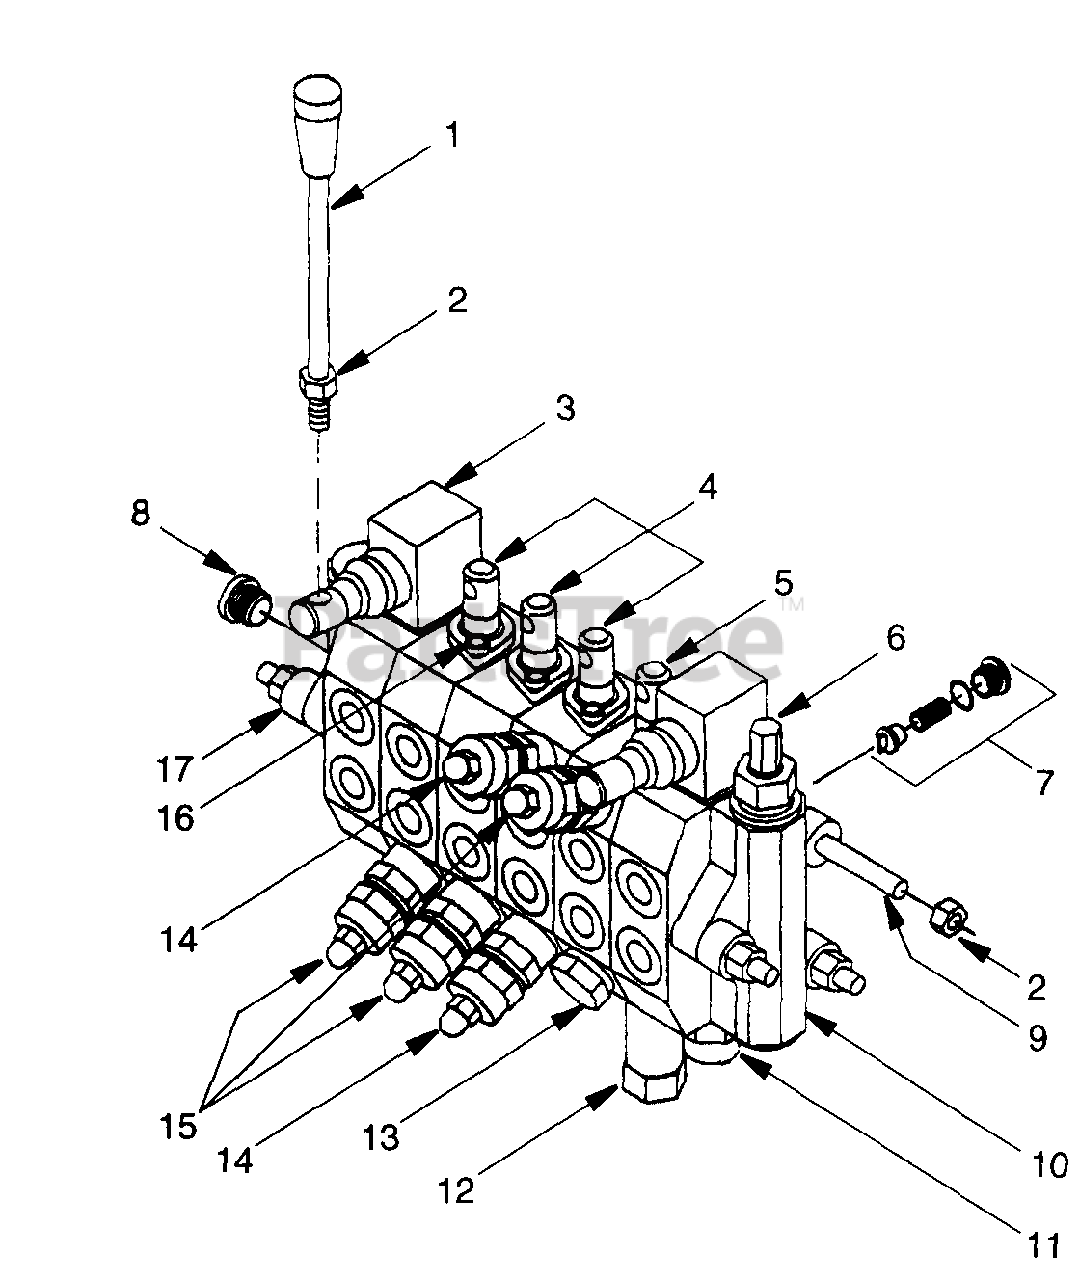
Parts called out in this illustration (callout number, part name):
1	Stabilizer Control Handle
2	Hex Nut, 8mm x 1.25P
3	Stabilizer Control Assy
4	Valve Spool Section w/Out Relief
5	Boom Section w/Relief
6	Relief Valve Assy
7	Check Valve Assy
8	Plug, 3/4 SAE M w/O-ring
9	Hex Hd Cap Scrw, 8mm x1.25P x 276mm
10	Valve Inlet Section
11	Spool Position Control Assy
12	Spool Position Control Assy
13	Plug, Port Relief Cavity
14	Port Relief Valve/Anit-Cav 2100psi
15	Shock Dampening Valve, 2500psi
16	Hex Hd Cap Screw, 5mm x.8P x 12mm
17	Valve Outlet Section
